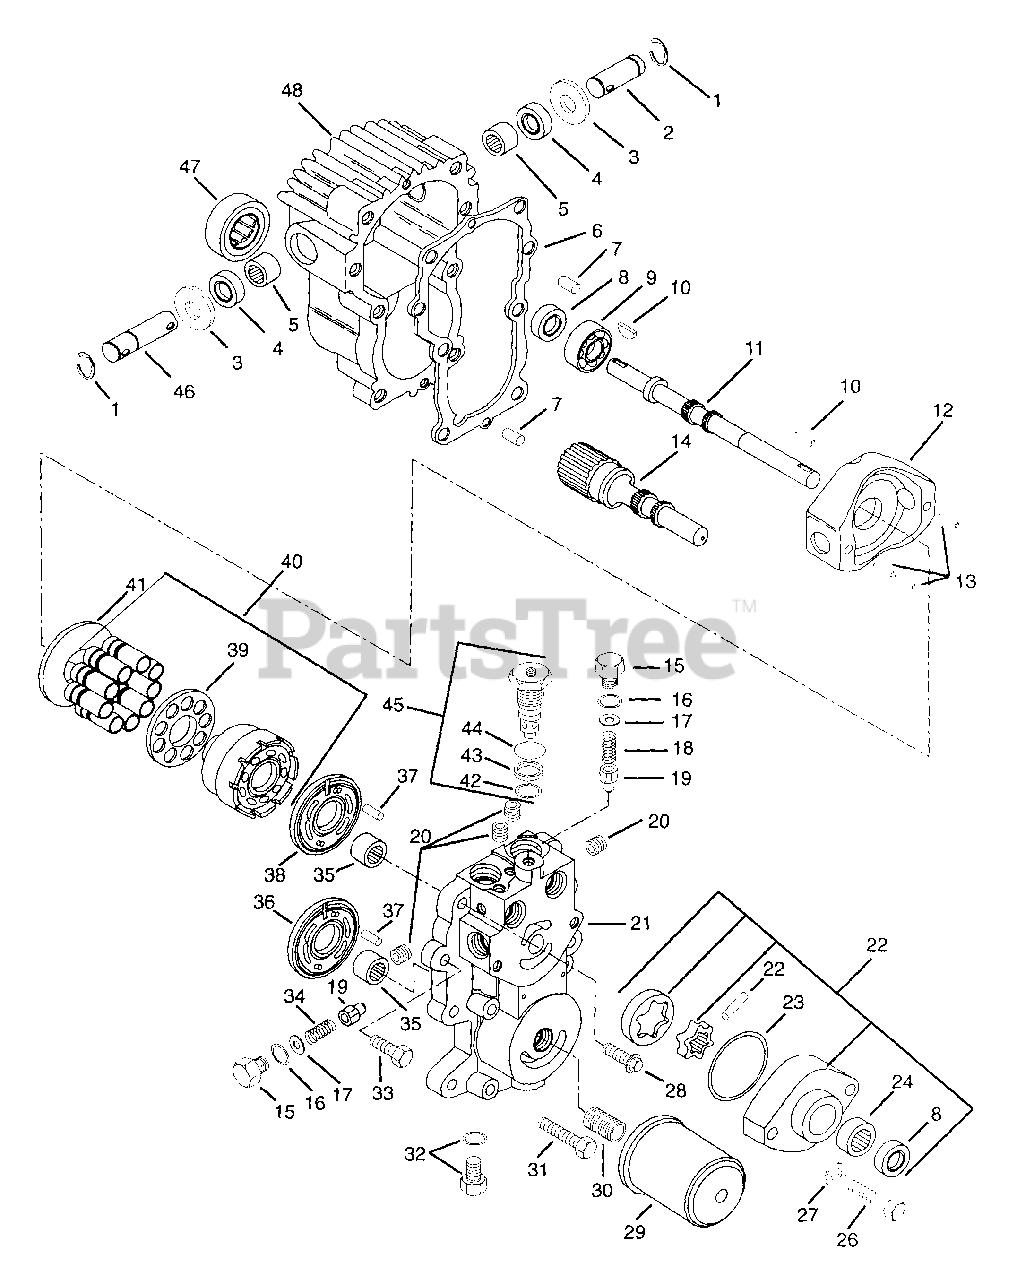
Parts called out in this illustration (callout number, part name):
1	RG-RTNG-EXT .688X.042
2	TRUNNION SHAFT
3	WSHR-FL-STL .699X1.375X.059
4	SEAL .625X1.187X.187
5	BRG-NEEDLE .688X.876X.63
7	DOWEL PIN
8	SEAL .625X1.128X.250
9	BRG-BALL 17MMX40MMX12MM
10	KEY-WDRF .188X.75X.313 SAE 9
11	PUMP SHAFT
12	SWASHPLATE VARIABLE
13	PIN-ROLL .188X.63
14	MOTOR SHAFT
15	PLUG-HEX HEAD
16	O-RING .414X.562X.072
17	SHIM PACKAGE
18	SG-COMP ??X??X?? SUNSTRAND
19	RELIEF VALVE CONE
20	PIPE PLUG
21	CENTER SECTION
23	O-RING 2.364X2.504X.072
24	BRG-NEEDLE .625X.875X.50
25	CHARGE PUMP ASSEMBLY
26	BLT-HEX .44-14X2.00 GR5
27	WSHR-FL-STL .469X.719X.108
28	SCR-12PNT .38-16X1.25 GR5
29	OIL FILTER
31	BLT-HEX .38-16X2.00 PL GR5
32	THREADED PLUG
33	BLT-HEX .38-16X1.50 PL GR5
34	SG-COMP ??X??X?? SUNSTRAND
35	BRG-NEEDLE 17MMX.938X.62
36	MOTOR VALVE PLATE
37	DOWEL PIN
38	VALVE PLATE
39	SLIPPER RETAINER
40	CYLINDER BLOCK KIT
41	THRUST PLATE
42	O-RING .614X.750X.070
43	O-RING .614X.750X.046
44	O-RING .770X.968X.097
45	CHECK VALVE ASSEMBLY
46	TRUNNION SHAFT
47	BRG-ROLLER 1.27X2.05X15MM
48	HOUSING W/SEALS AND BEARINGS
